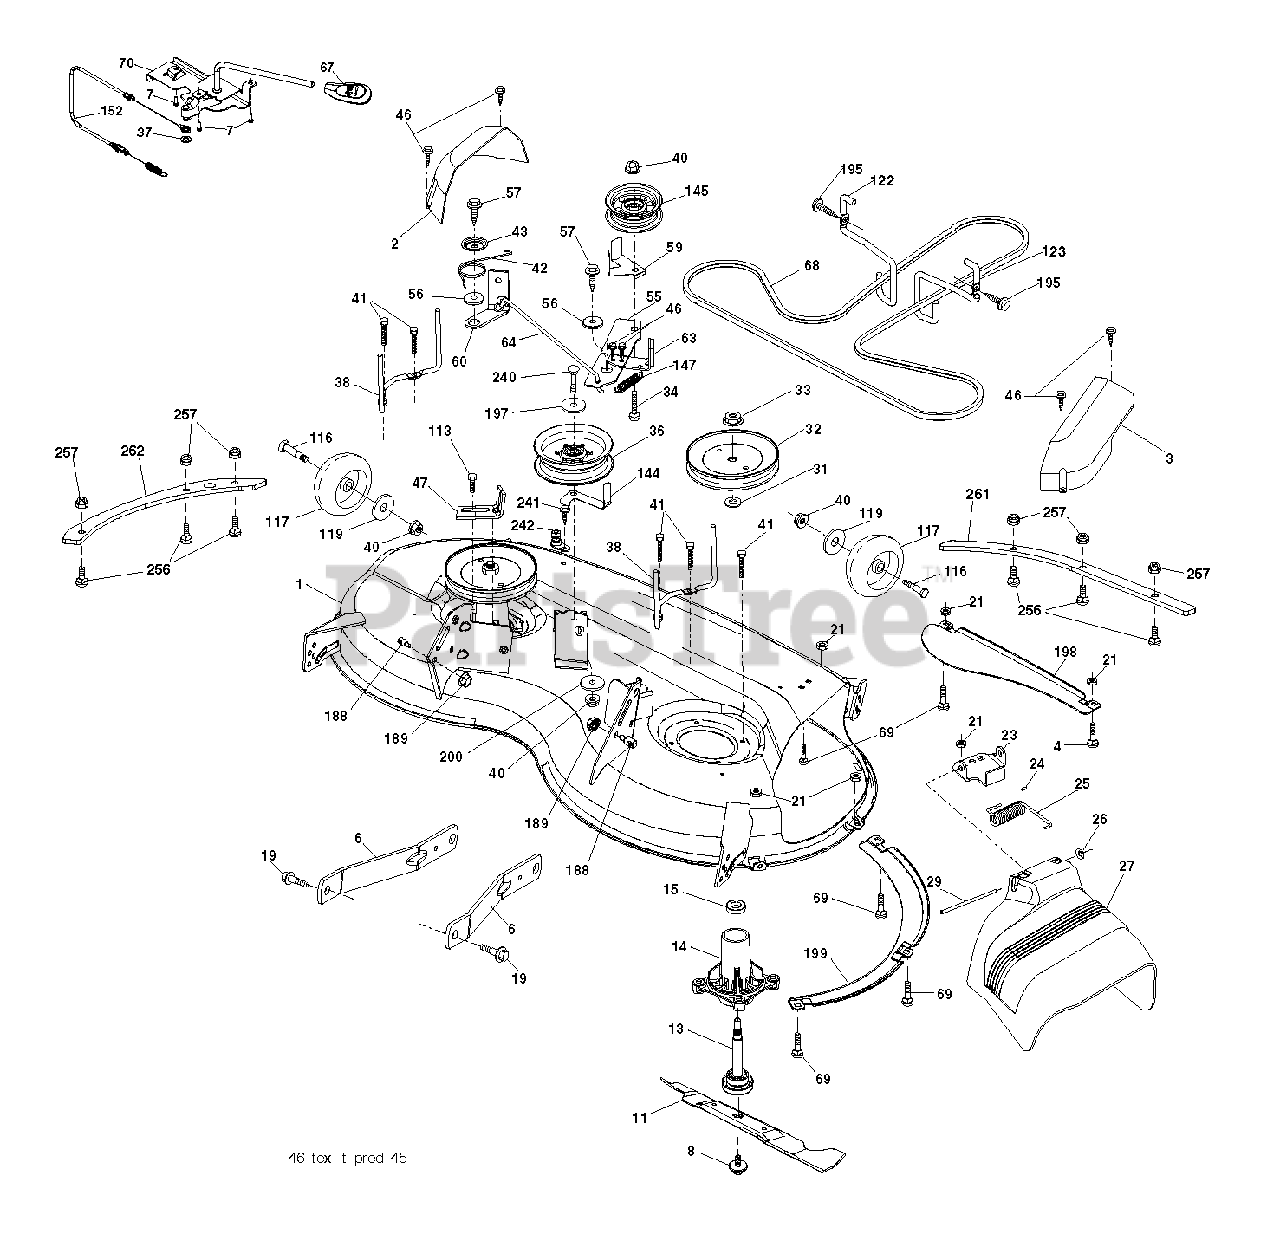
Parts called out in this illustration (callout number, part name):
1	Mower Deck Assembly, 46"
2	COVER MANDREL RH
3	COVER.MANDREL.LH.46"
4	BOLT
6	ARM.SUSPENSION.MOWER.R
7	SCREW.#10 X 0.750.BOS THREAD
8	BOLT.WASHER.ASM.7/16-2
11	BLADE 46" HI LIFT
13	SHAFT.ASM.MDRL.N/GREASE.38
14	HOUSING MANDREL
19	BOLT.SHOULDER
21	LOCKNUT
23	BRKT.DEFLECTOR.38"2005+
24	CAP-SLEEVE LT
25	SPRING.TORSION.DEFLECT
26	NUT PUSH M
27	SHIELD.DEFLECTOR.MOWER.46"BLAC
29	ROD.HINGE
31	WASHER.SPACER.MANDREL
32	PULLEY.MANDREL.5.438.PD
33	NUT.FLANGE.LOCK.TOP
34	BOLT.3/8-16X1.50
36	PULLEY.IDLER.2006
38	KEEPER.BELT.MANDREL.PULLEY
40	NUT LOCK FLG 3/8-16 UNC
41	Hex Washer Head Bolt, .313-18 X 1.19
42	SPRING.TORSION.BRAKE
43	SRPING.TORSION.RETAINE
46	SCREW.1/4-20X5/8
47	BRKT.CLUTCH.CABLE
55	IDLER.ARM
56	SPACER.RETAINER
57	SCREW 3/8-16X1
59	GUARD, BELT
60	ARM BRAKE MOWER RH 38"
63	ARM BRAKE MOWER
64	LINKAGE BRAKE
67	HANDLE.CLUTCH.CABLE.LT
68	V BELT
69	BOLT
70	CLUTCH.ASM.MANUAL.YT.PREDATORQ
113	BOLT.5/16HEX.WHS.HD
116	BOLT.SHOULDER.3/8-16X3-5/8
117	WHEEL. GUAGE RALLY
122	KEEPER BELT ENGINE LH
123	KEEPER BELT RH
144	KEEPER.BELT.MOWER
145	PULLEY.IDLER.48"PRIMARY
147	SPRING RETURN
152	Mechanical Clutch Cable
188	STUD.FASTNER.W/ANTI-ROTATE
189	NUT LOCK HEX FLANGE 5/16-18
195	SCREW, 3/8-16X3/4
197	WASHER
198	BAFFLE CENTER FRONT
199	BAFFLE FRONT RH
200	WASHER.13/32 X 1 X 1/2.11GUARD
240	BOLT-HEX EAK
242	PORT.WASHOUT
256	Buttonhead Screw, 5/16-18
257	NUT T
261	Deck Reinforcement Plate, 46 F
262	Side Reinforcement Plate, 46" Bolt-on
